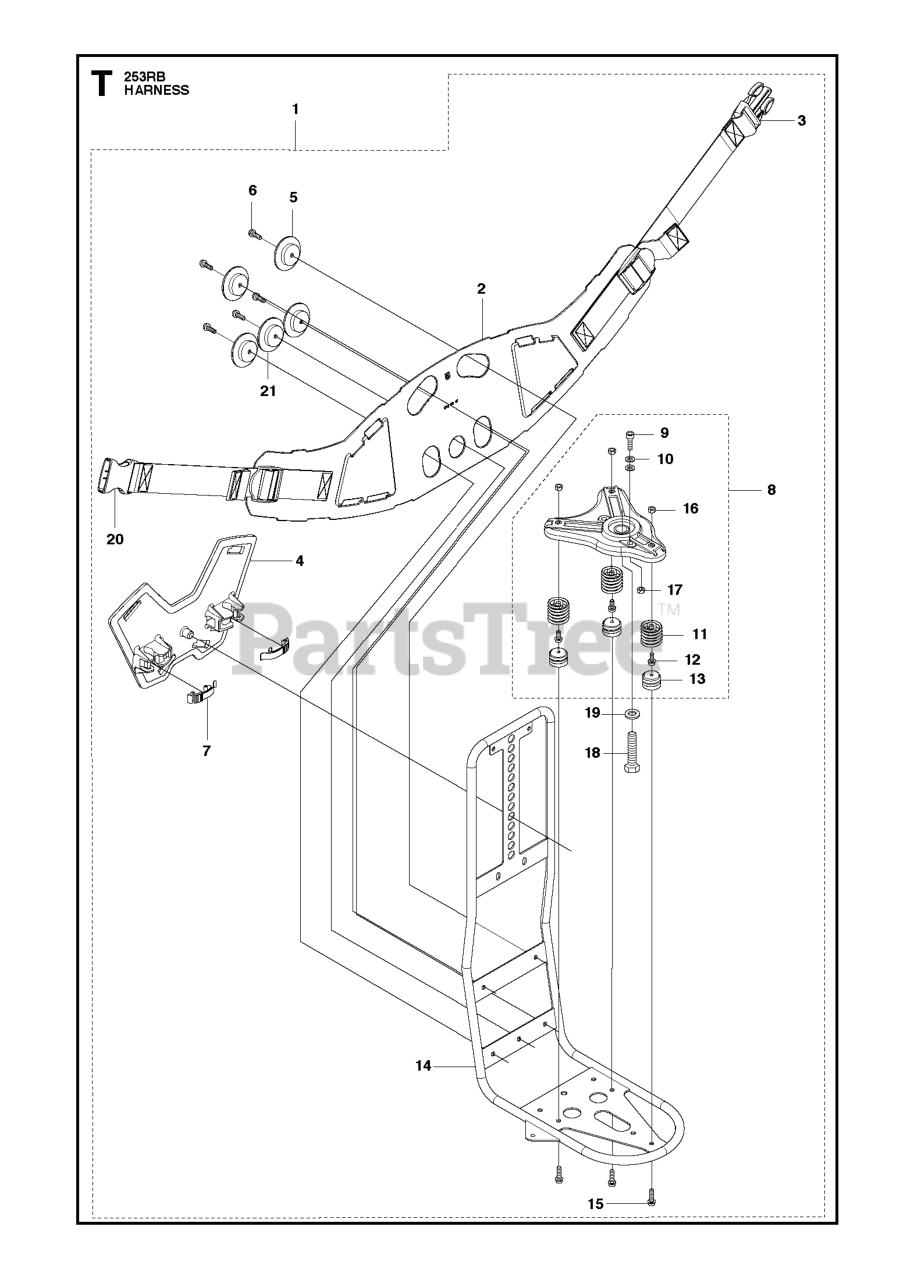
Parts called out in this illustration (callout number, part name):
3	BUCKLE, MALE
9	SCREW IHSCM
10	WASHER - M6
18	Screw M10x25
19	WASHER
20	BUCKLE, FEMALE
